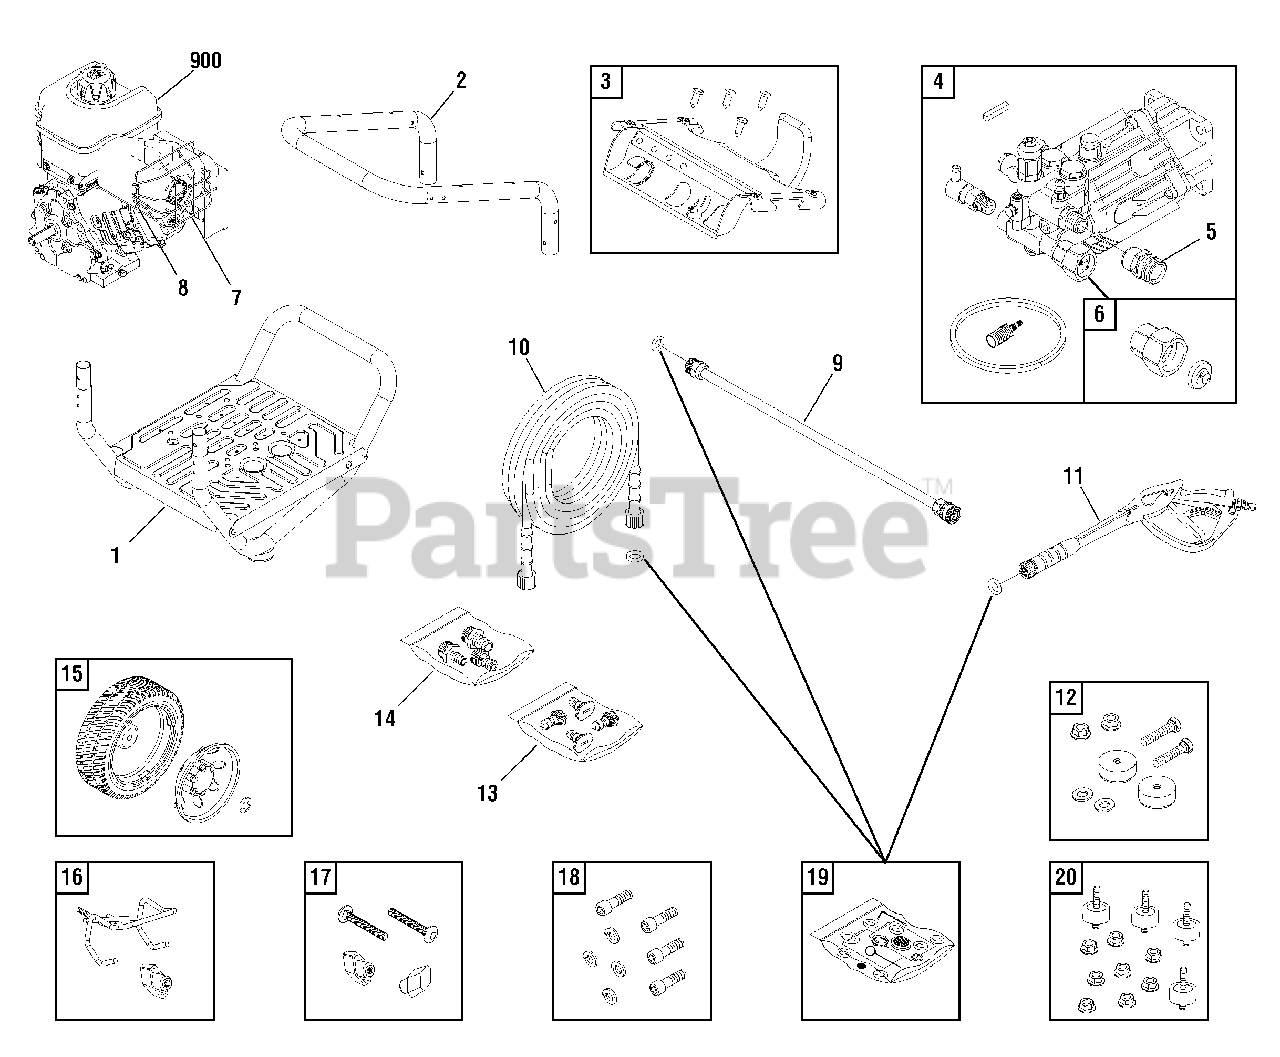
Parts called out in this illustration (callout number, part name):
6	CONNECTOR-GRDN HOSE
7	GUARD-MUFFLER
9	EXTENSION-QC
12	MOUNT-VIBRATION
13	KIT-QC NOZZLES
14	KIT-GARDEN HOSE
15	KIT-WHEEL
17	KIT-HARDWARE HANDLE
18	KIT-HARDWARE, PUMP MOUNTING
20	KIT- VIBRATION MOUNT
900	* ENGINE
